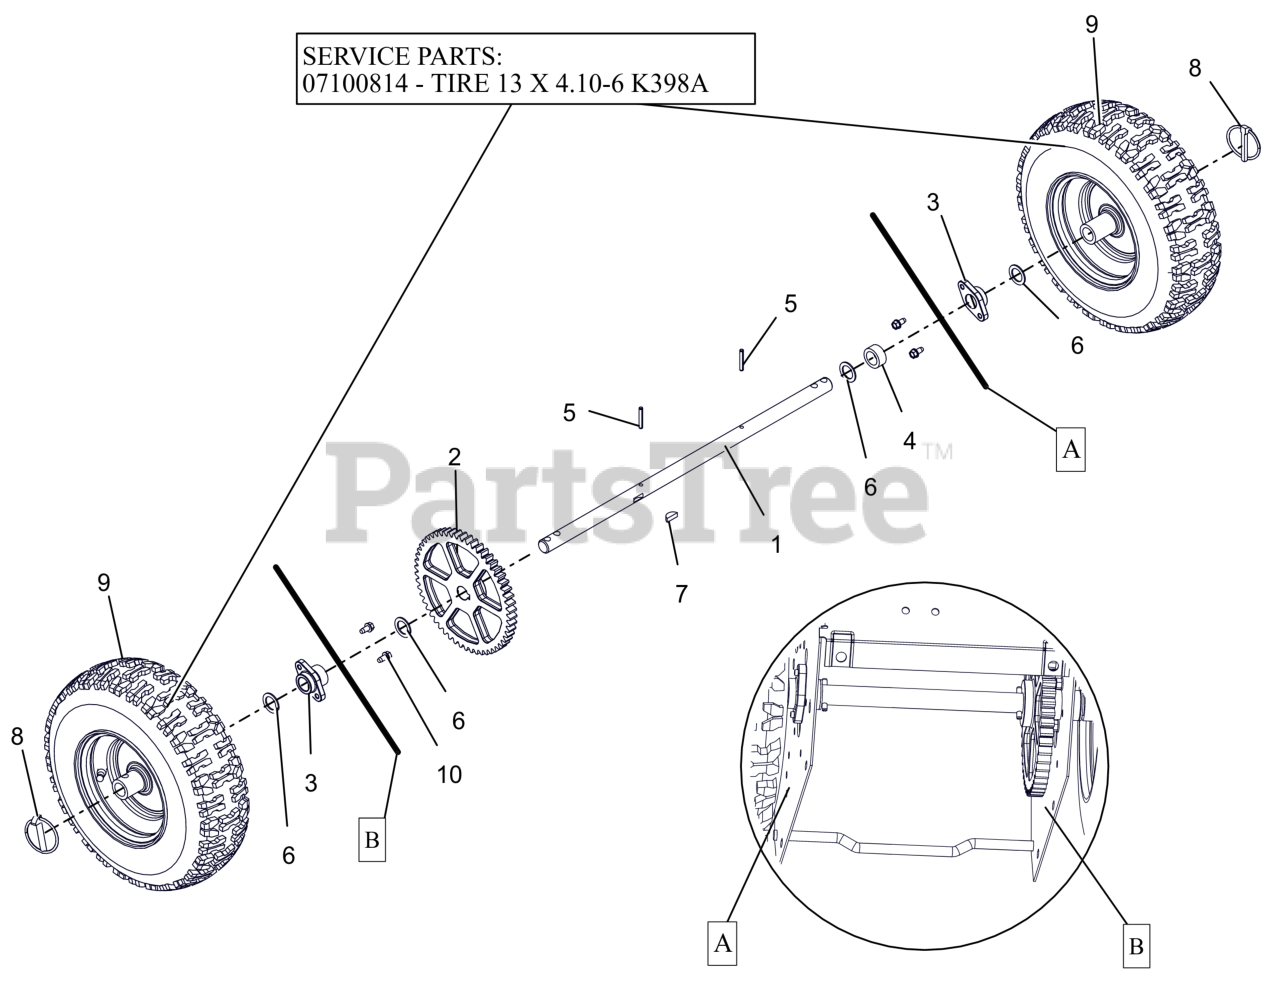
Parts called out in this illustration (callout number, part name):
1	SHAFT, AXLE
2	SPUR GEAR, 54T .75ID X 6.75PD
3	BSHG .75X1.125X.65
4	BSHG-SLV .766 X 1.125 X .500
5	PIN-ROLL .188X1.25
6	WSHR, FLT .754X1.125X.062 ZCC
7	KEY-WDRF .25X.750X.313 SAE91
8	PIN-LOK .31X1.75
9	TIRE/WHEEL, 13X4.10-6
9	TIRE, 13" K398A
10	SCR-TAP .25-20X.50 HWH ZCC
